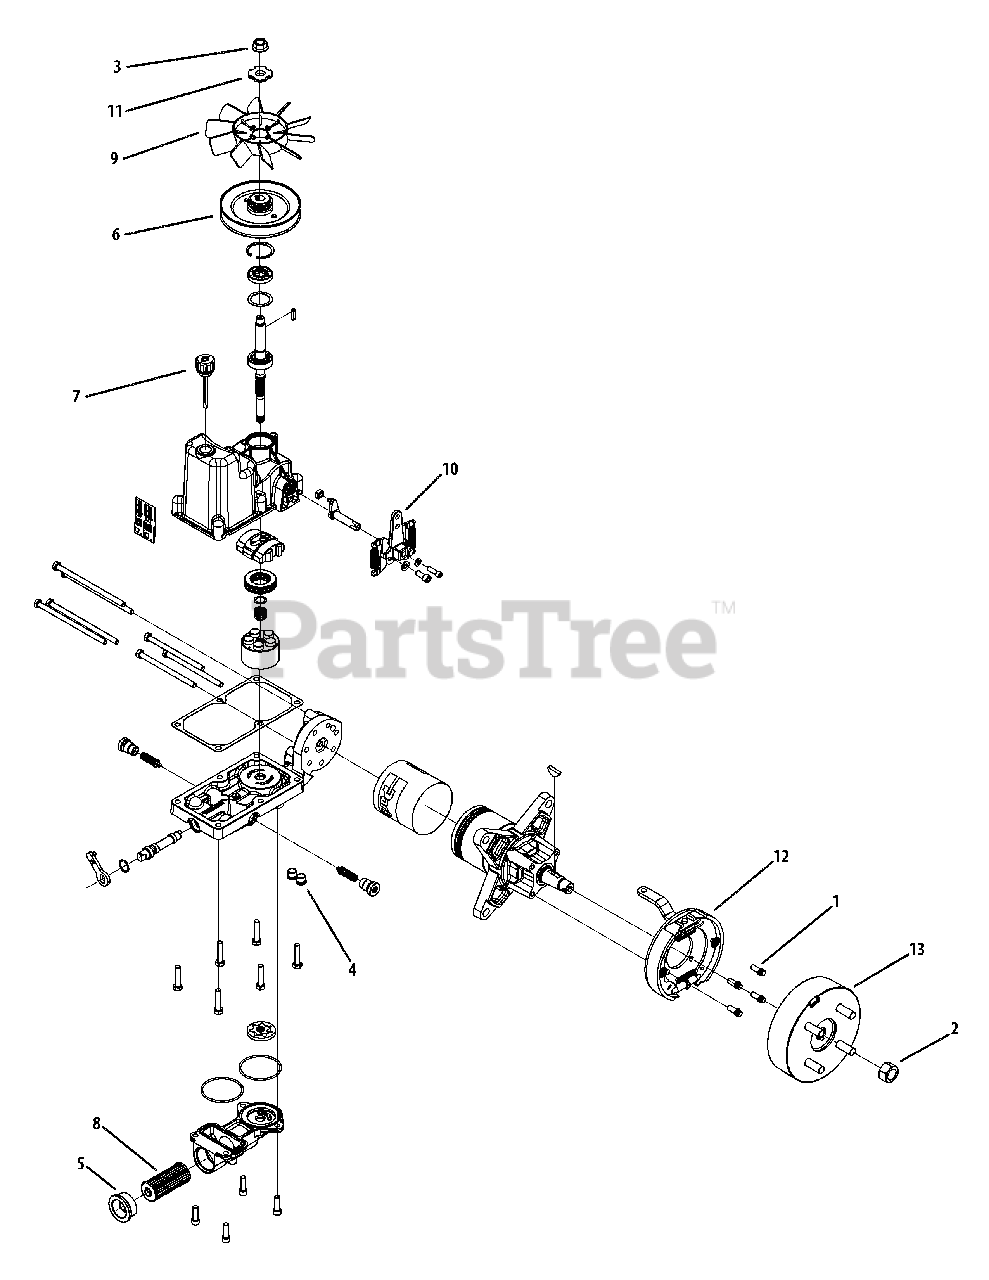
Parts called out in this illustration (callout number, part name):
1	Flange Head Screw
3	Nut, Flange 1/2-20 UNF
4	Plug, Magnetic Hex
5	Plug & O-Ring Assembly
6	Pulley (5")
7	Breather
11	Fan Spacer
12	Brake Assembly
13	Drum Assembly, 4 Bolt, 1" Shaft
